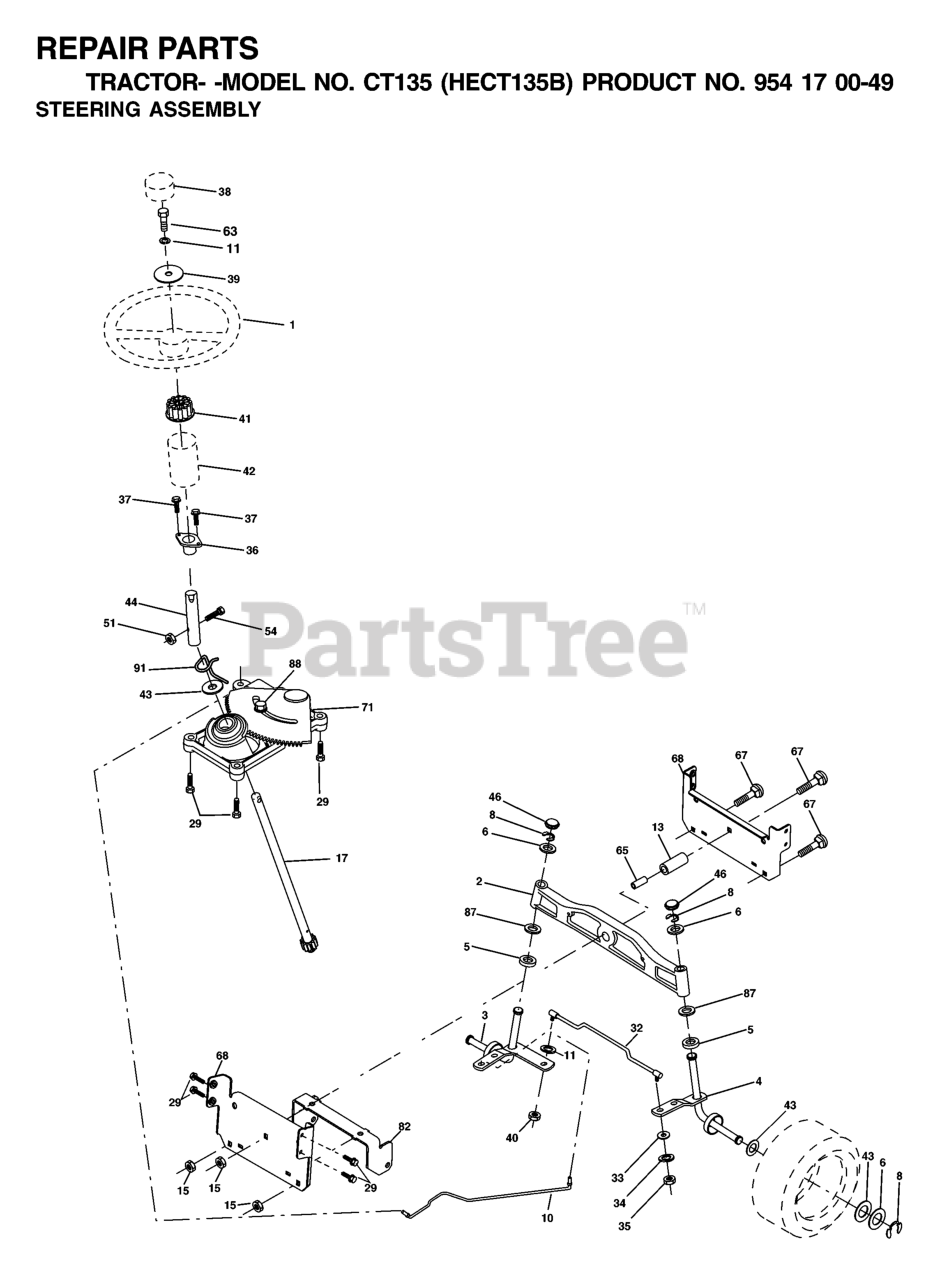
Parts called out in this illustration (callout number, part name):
1	STEERING WHEEL
2	AXLE ASM
3	SPINDLE.ASM.LH.15"TIRES
4	SPINDLE.ASM.RH.15"TIRES
5	THRUST WASHER
10	DRAGLINK.15".TIRES.2001
11	WASHER, LOCK 3/8
13	TUBE, PIVOT AXLE
15	NUT
17	SHAFT ASM
29	SCREW 3/8-16X3/4
32	ROD.ASM.TIE.BALL.JOINT.NOVAN
33	WASHER M
34	WASHER.LOCK.HVY.HLCL.SPR.5/16
35	NUT, CROWNLOCK
36	BUSHING, STEERING
37	SCREW.TT.#10-32X.5.3/8.FLANGE
38	CAP.WHEEL.STEERING.GREY
39	Washer 13/32 x 1-1/20 x 11 Gauge
40	GRIPCO NUT
41	STEERING WHEEL ADAPTOR
42	BOOT STEERING
44	EXT SHAFT STEERING
46	CAP.SPINDLE.BLACK
51	NUT.71038.31-18.HEX.NYLOCK
54	BOLT.5/16-18X1-1/4 FULL.THREAD
65	SPACER BRACE AXLE
67	BOLT
68	BRACE.AXLE.15"TIRES
71	STEERING ASM
82	BRACKET
87	WASHER, FLAT .781 X 1 1/2"
88	BOLT, SHOULDER 7/16-20
91	CLIP.STEERING
